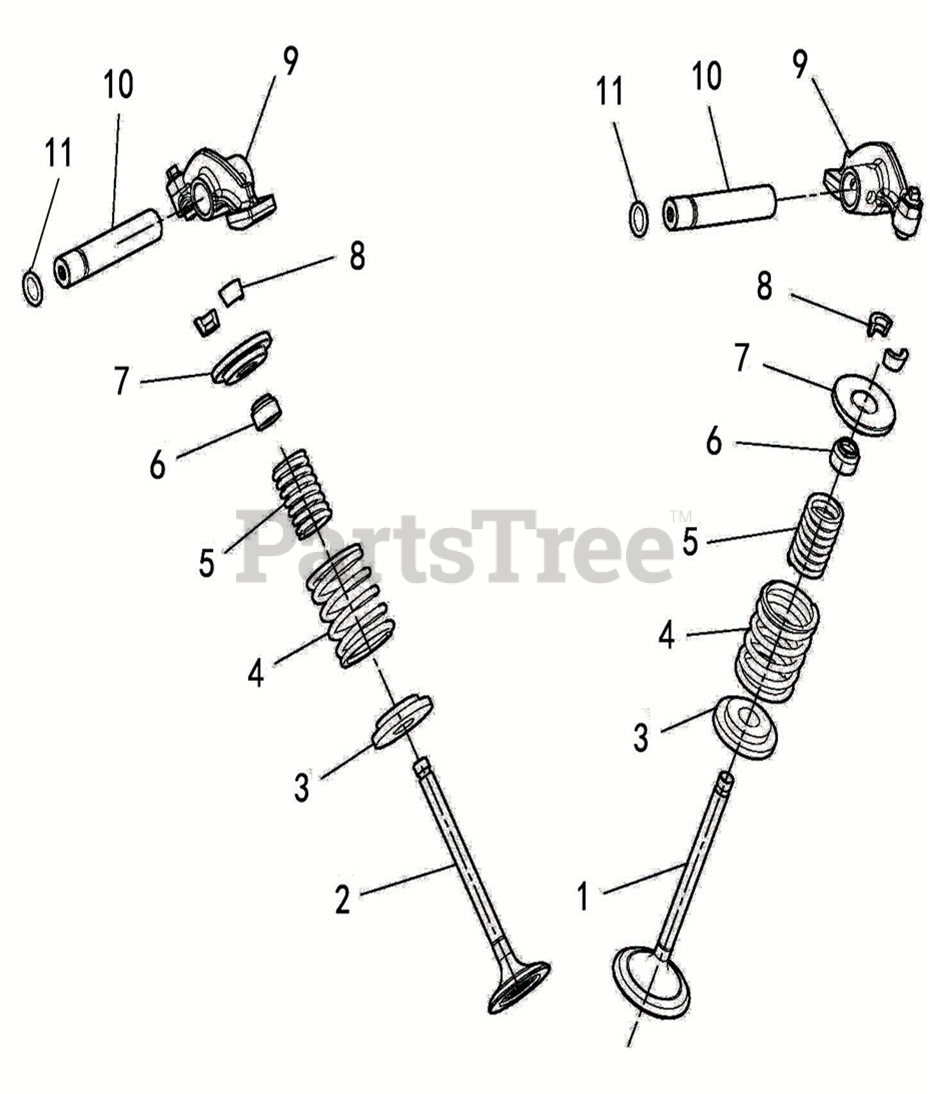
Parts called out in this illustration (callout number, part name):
1	INTAKE VALVE
2	EXHAUST VALVE
3	VALVE SPRING WASHER
4	VALVE OUTER SPRING
5	VALVE INNER SPRING
6	VALVE STEM SEAL
7	RETAINER VALVE SPRING
8	VALVE COLLAR
9	ROCKER ARM ASSEMBLY
10	VALVE ROCKER SHAFT
11	O-RING 9X2
